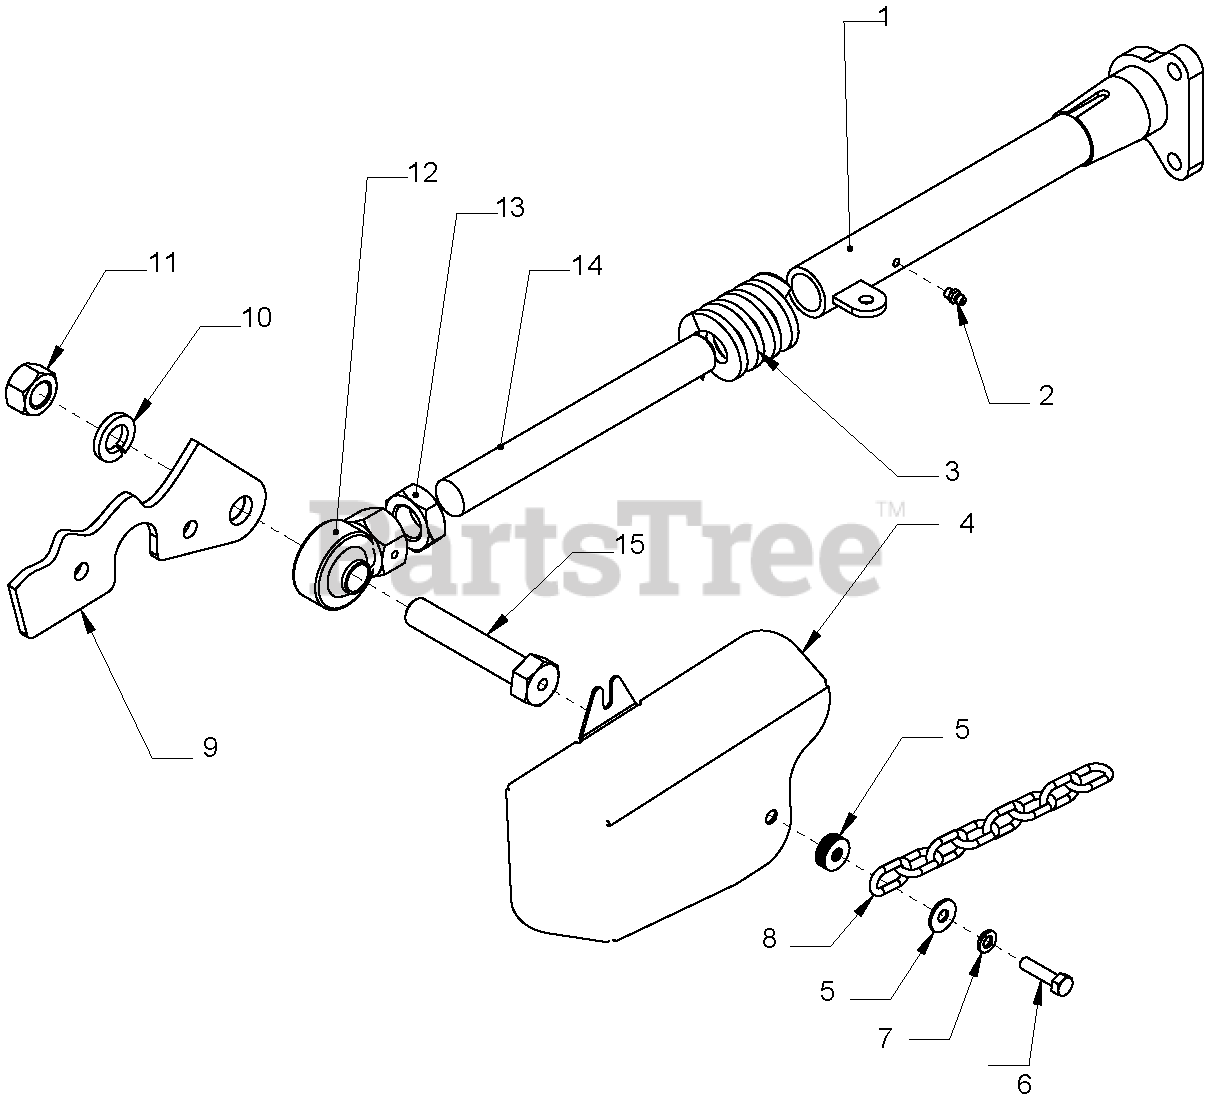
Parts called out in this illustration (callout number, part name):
1	V-Cut Telescoping Arm
2	Grease Fitting, 1/4-28
3	Die Spring, Compression
5	Washer, Flat 5/16 USS CP
6	Cap Screw, Hex Head 5/16-18 x 1-1/4
7	Washer, Lock 5/16 CP
8	Safety Chain, 8 Links
10	Washer, Lock, 3/4 CP
11	Nut, Hex 3/4-10 CP
12	Ball Socket Weldment
13	Jam Nut, 1-8 Nyloc
14	Telescoping Arm Shaft
15	Bolt, Pivot
